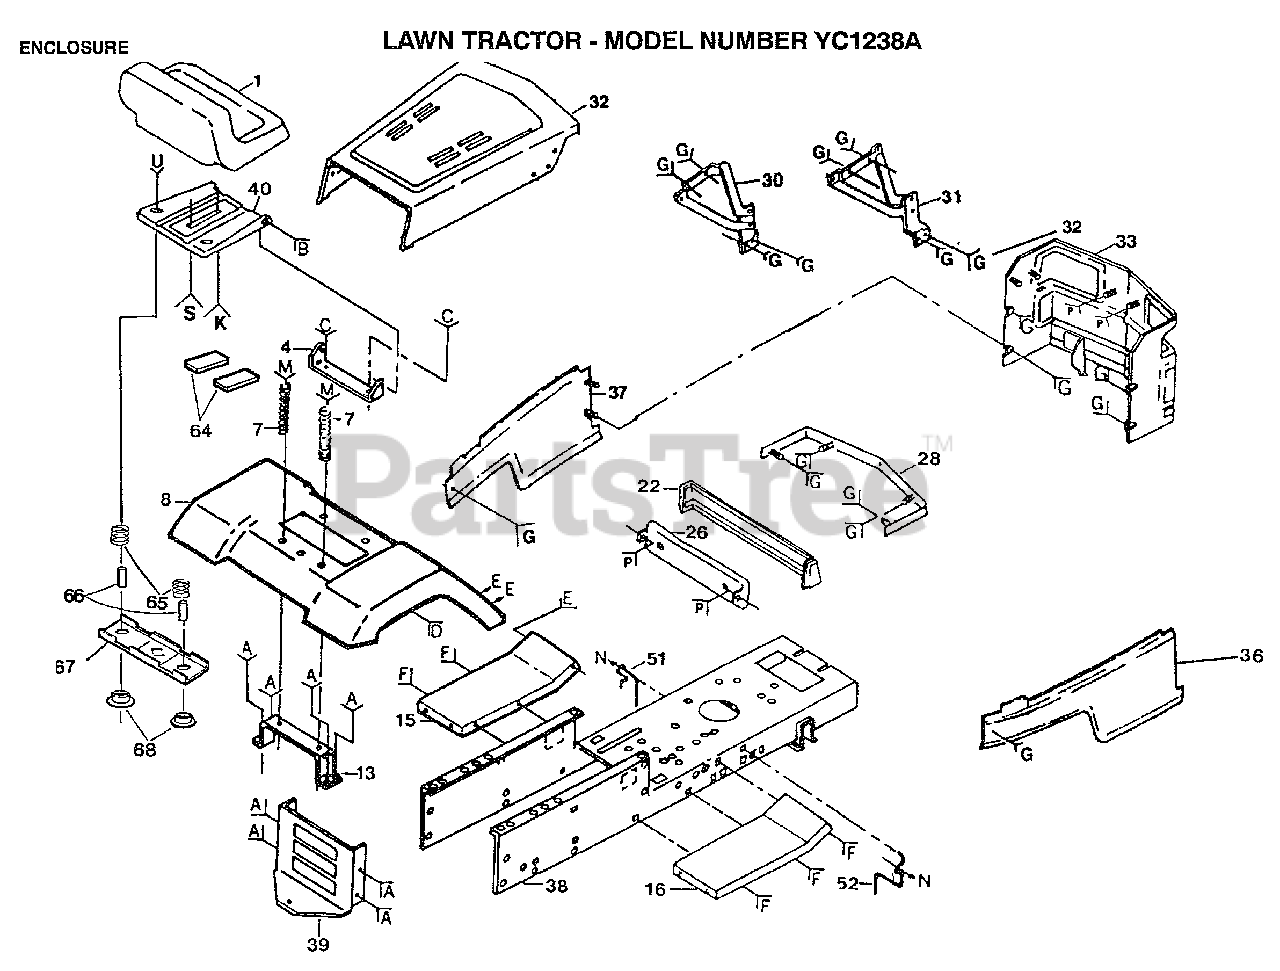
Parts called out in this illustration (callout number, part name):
2	SCREW
3	SCREW GTV
7	SPRING COMPRESSIO
9	WASHER
12	SCREW LT
14	"BOLT,SHOULDER"
17	BOLT
21	PAL NUT LT
24	WASHER
27	BOLT
28	"STRAP,GRILL T"
30	"HINGE,HOOD,LH T"
31	"HINGE,HOOD,RH T"
38	CHASSIS ASS'Y
47	WASHER
48	LOCKWASHER
49	WASHER
50	BOLT
51	BELT GUIDE
52	BELT GUIDE
59	WASHER
60	WASHER PM
62	BOLT
64	STRIP FORM
65	SPRING
66	SPACER SPLIT
67	BRKT SWITCH
68	BUSHING
